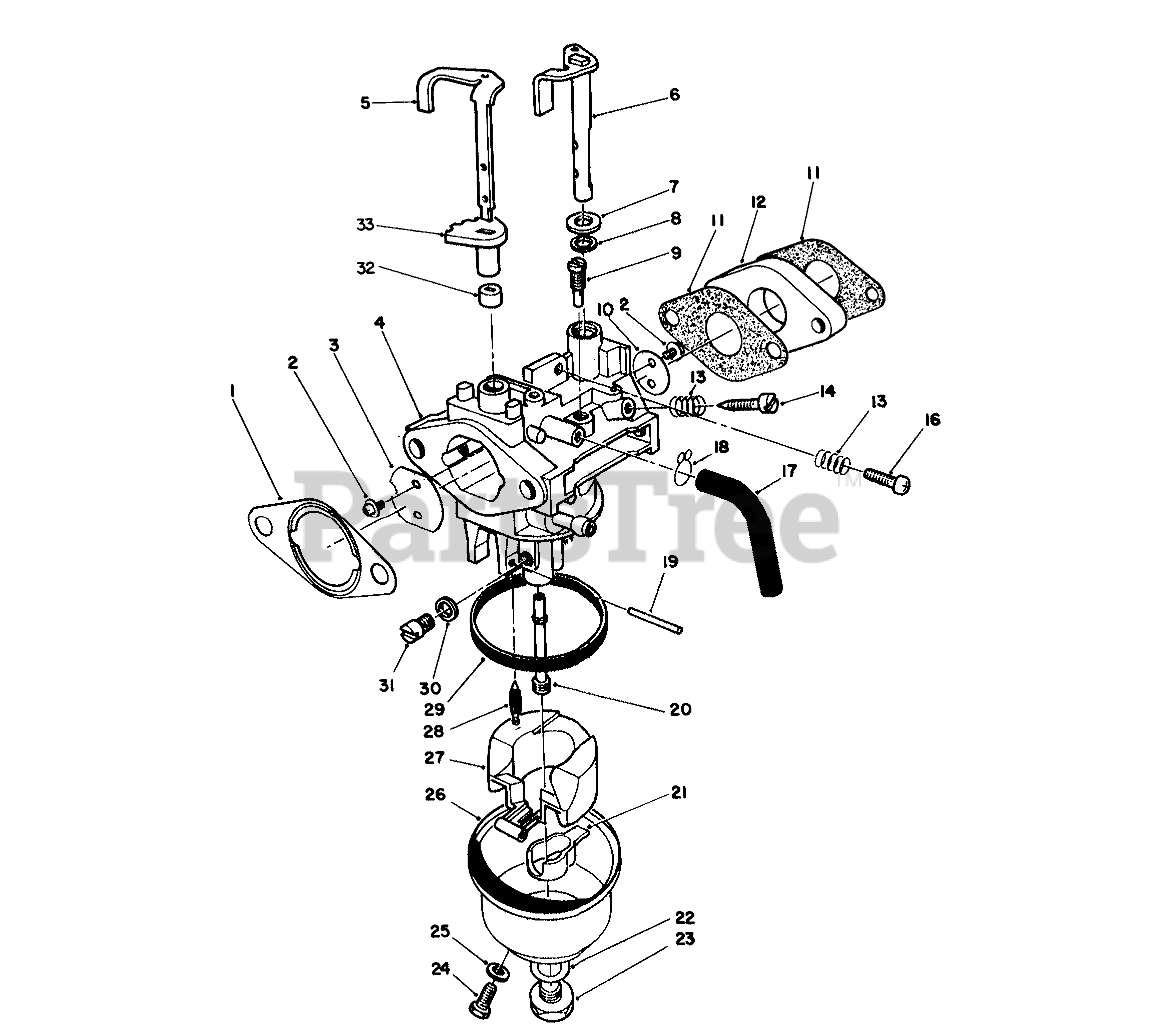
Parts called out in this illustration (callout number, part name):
1	GASKET F/W ENGINE
2	Screw
3	VALVE
4	Body-Carburetor
5	Shaft-Choke Valve
6	SHAFT
7	WASHER
8	Seal-Throttle Shaft
9	JET - PILOT
10	VALVE
11	GASKET INTAKE
12	INSULATOR - CARB.
12	CARB INSULATOR
13	SPRING-PILOT SCREW
14	ADJUSTER
16	SCREW
18	CLAMP
19	Pin
20	NOZZLE - MAIN
21	SPACER
22	GASKET
23	SCREW
24	SCREW
25	GASKET
27	FLOAT
28	NEEDLE
29	FLOAT BOWL GASKET
30	SPACER
31	JET-HIGH ALTITUDE
32	LOWER CHOKE RING
33	UPPER CHOKE RING
